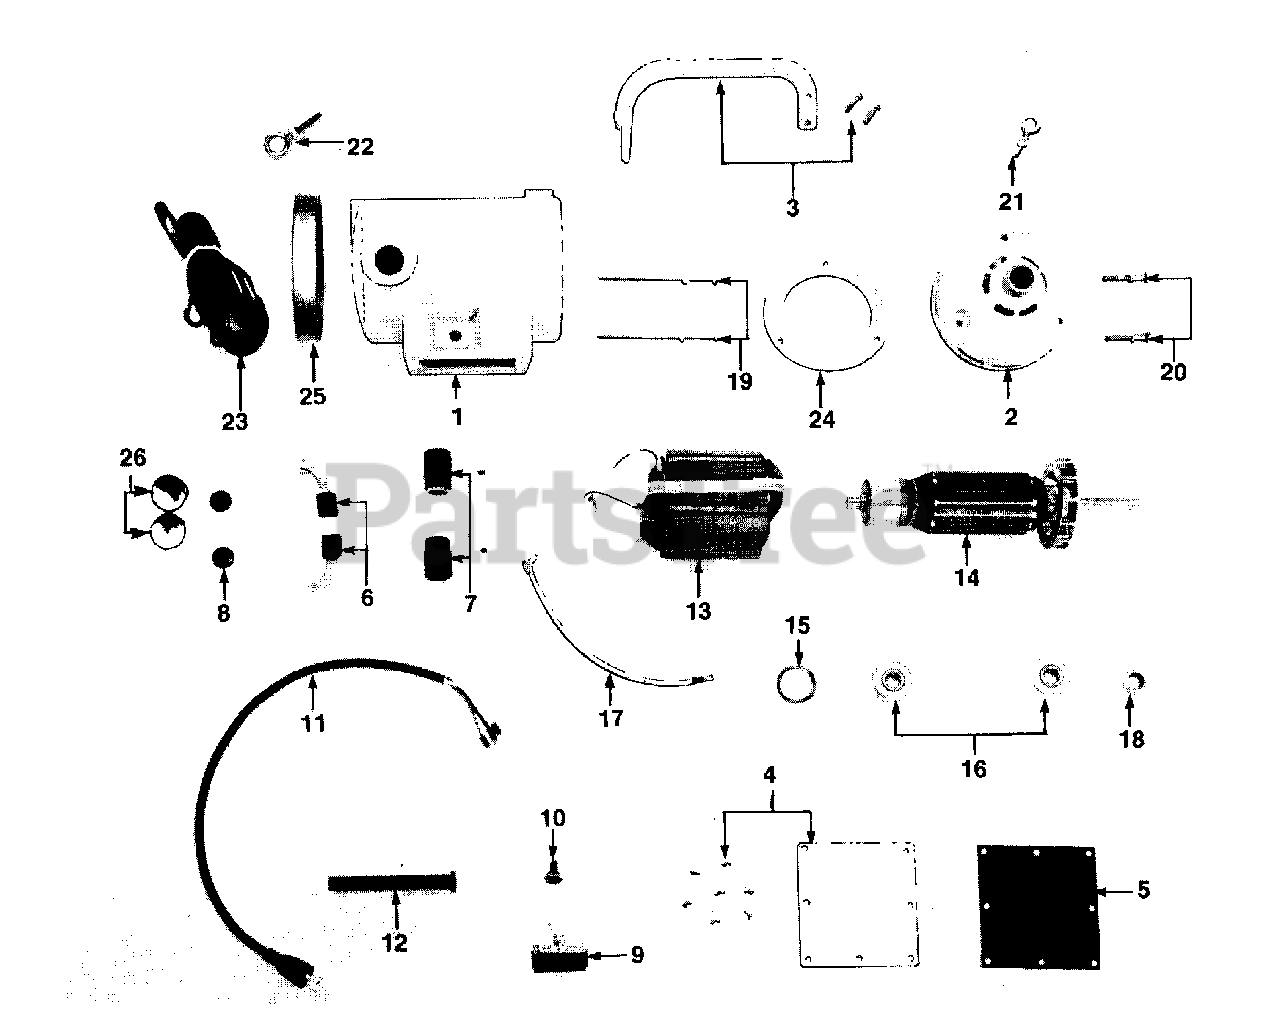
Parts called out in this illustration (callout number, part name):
1	HOUSING- Motor
2	END BELL- w/grease seal
3	HANDLE- Motor
4	PLATE- Base cover (w/screws)
5	GASKET- Cover plate
6	BRUSH- Motor
7	HOLDER- Brush
8	CAP- Brush holder
9	SWITCH- Electric
10	BOOT-Rubber switch
11	CORD- Switch
12	PROTECTOR- Rubber
13	COIL- Field
14	ARMATURE- w/fan
15	SPRING- Rear bearing thrust
16	BEARING- Motor (2 required)
17	LEAD- Brush
18	SEAL- Grease
19	BOLT- Field coil (10-24 x 4 3/4") (2 required)
20	BOLT- End bell (1/4-20 x 13/4") (2 required)
21	EYEBOLT- w/nut (2 required)
22	EYEBOLT- Carrying strap
23	STRAP- Carrying
24	BAFFLE- Vent
25	COVER- Rear motor
26	CAP- Metal
